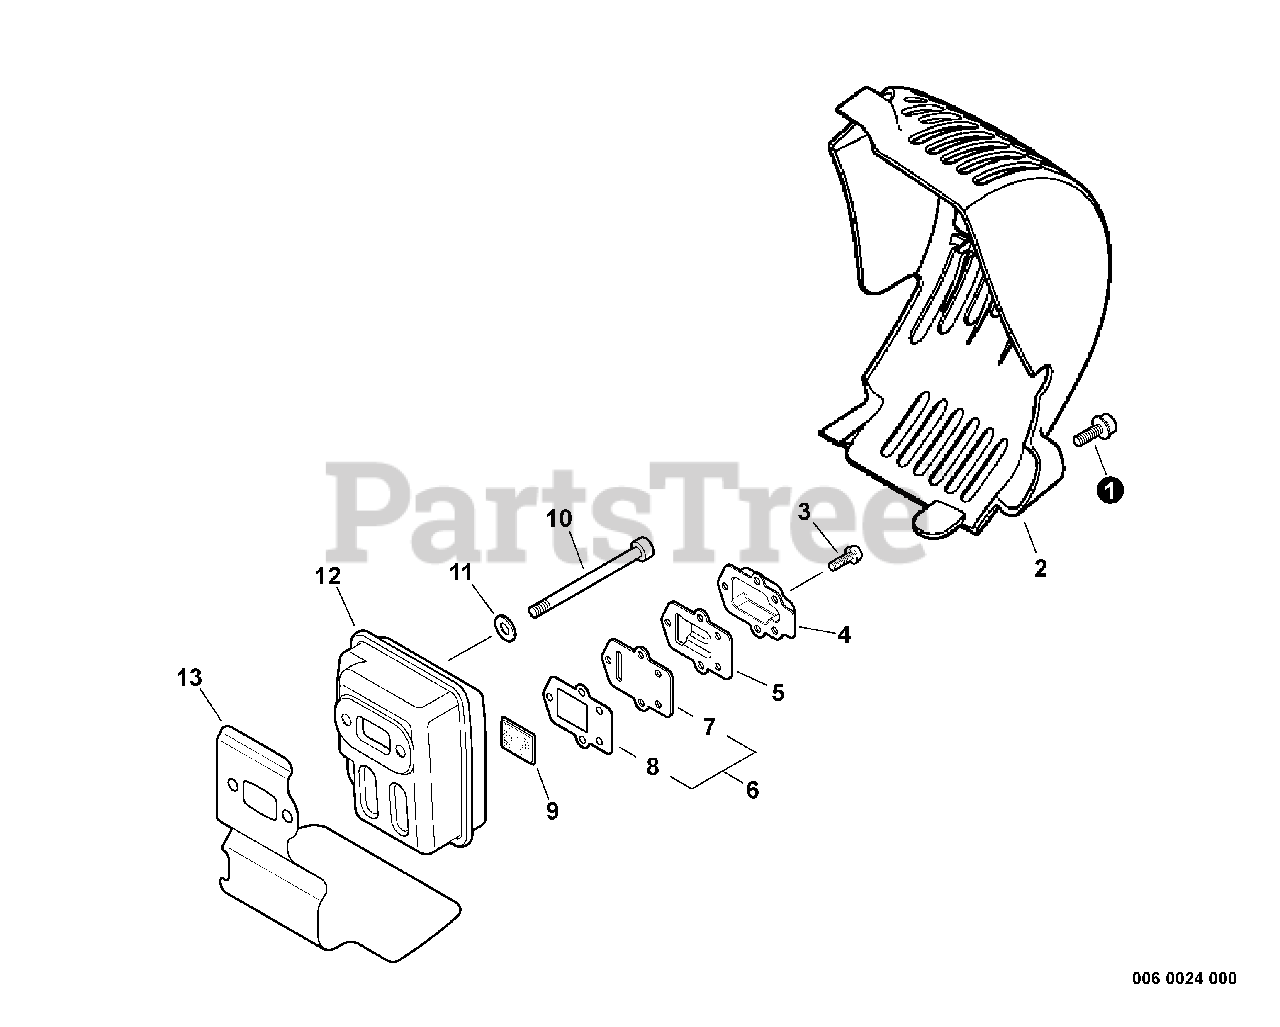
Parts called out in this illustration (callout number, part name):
1	SCREW - 5X14
2	COVER, EXHAUST
3	SCREW - 4X10
4	GUIDE, EXHAUST - OUTER
5	GUIDE, EXHAUST - INNER
6	EXHAUST GUIDE KIT
7	GUIDE, EXHAUST
8	GASKET, EXHAUST
9	SCREEN, SPARK ARRESTOR
10	SCREW - 5X55
11	WASHER - 5
12	MUFFLER
13	SHIELD, EXHAUST
